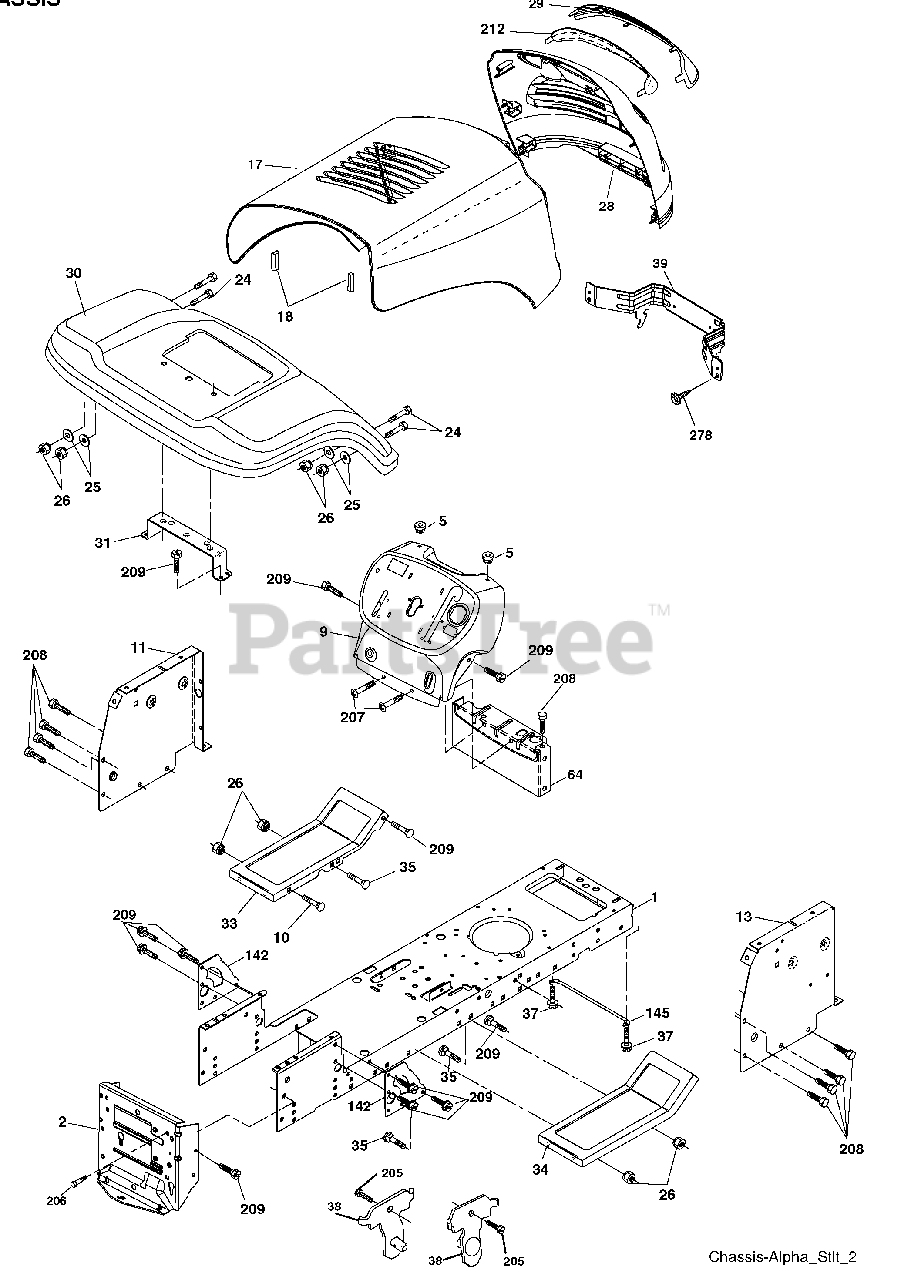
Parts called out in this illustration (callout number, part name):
1	Chassis
2	Drawbar, Stretch
5	Bumper, Hood/Dash
9	Dash
10	Bolt, Carriage 3/8-16 x 1
11	Panel Dash LH
13	Panel Slkscr Dash RH
17	Hood
18	Bumper Hood
24	Bolt Fin Hex 3/8-16 unc x 1 Gr. 5
25	Washer 13/32 x 13/16 x 12 Ga.
26	Nut Lock Hex w/Ins 3/8-16 unc
28	Grille/Lens Asm
29	Lens Grille Basic Bar
30	Fender
31	Bracket Fender Repl 109873X
33	Footrest Pnt LH
34	Footrest Pnt RH
35	Bolt Rdhd Sht Sqnk 3/8-16 x 3/4
37	Screw Thdrol 5/16-18 x 1/2 TYT
38	Bracket Asm. Pivot Mower
39	Bracket Pivot
64	Dash Lower
142	Plate Reinforcement
145	Rod Pivot Chassis/Hood
205	Screw Thdrol 3/8-16 x 1/2
206	Bolt Shoulder 5/16-18
207	Screw Thdrol 5/16-18 x 1/2
208	Screw Thdrol 3/8-16 x 1/2
209	Screw Hex Wsh Thdrol 3/8-16
212	Insert Lens Reflect
278	Screw #10 x 0.750 Single Lead-Hex
278	Plug Button Blk 359 Dia Choke
278	Plug Dome Plastic
